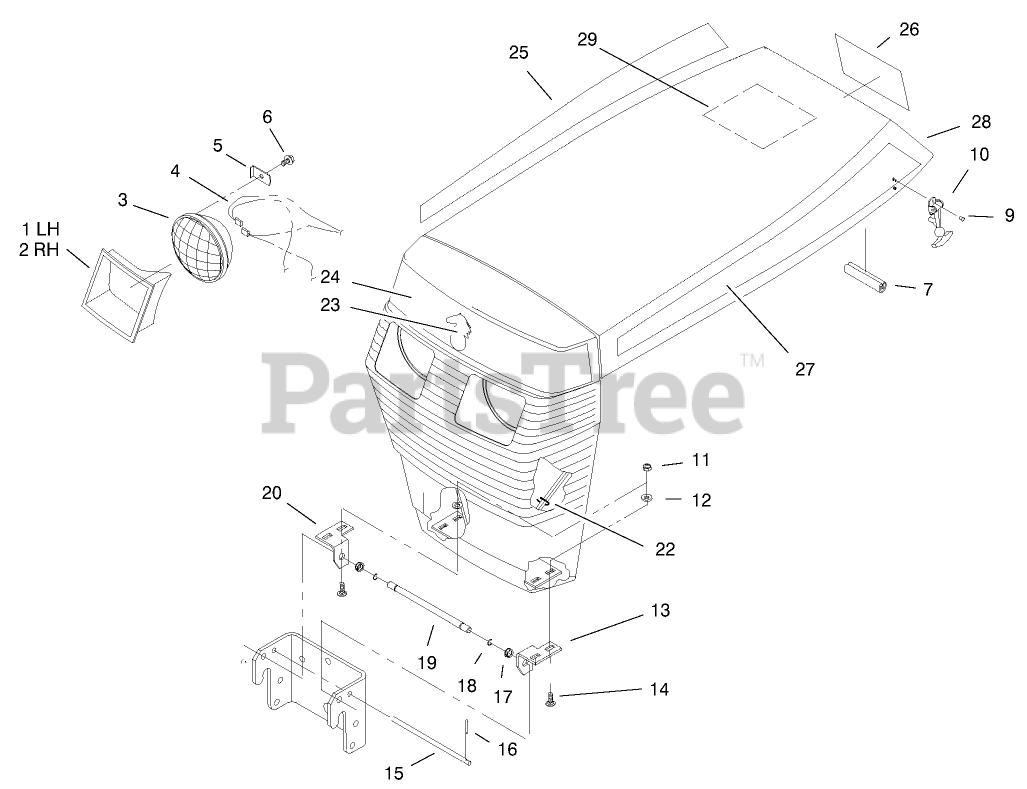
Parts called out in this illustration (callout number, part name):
3	HEADLAMP
4	HARNESS-HEADLIGHT
5	LOCK-HEADLIGHT
6	SCREW-HWH
7	EDGING-CONSOLE
9	RIVET-POP
10	HANDLE ASM
11	NUT-LOCK, NI
12	WASHER-FLAT
13	BRACKET-GRILL, LH
15	ROD-HOOD STOP
16	PIN-COTTER
17	BUSHING-NYLINER
18	RING-RETAINING
19	ROD-GRILL PIVOT
20	BRACKET-GRILL, R H
22	TIE-CABLE
24	DECAL-FRONT HOOD, TOP
26	DECAL-DANGER, HOOD
28	Hood
29	DECAL-MAINTENANCE
